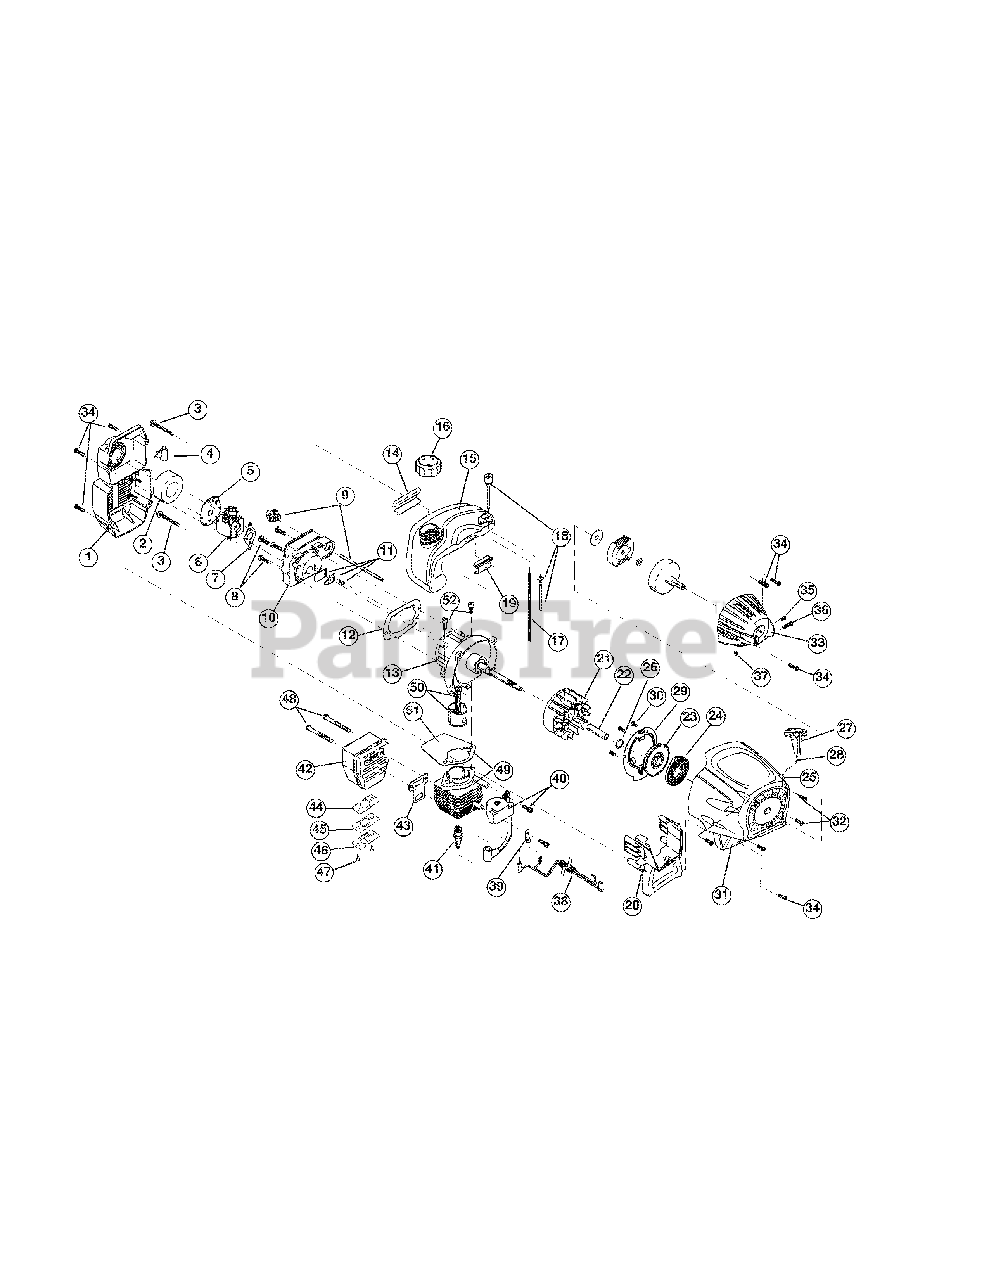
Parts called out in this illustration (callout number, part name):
1	Air Cleaner Cover Assembly (includes 2 & 34)
2	Air Cleaner Filter
3	Carburetor Mounting Screw Assembly
4	Choke Extension
5	Choke Plate
6	Carburetor Assembly (includes 7 & 18)
7	Carburetor Gasket
8	Carb Mount Screw
9	Primer & Hose Assembly
10	Carb Mount Assembly (includes 8, 11 & 12)
11	Reed Assembly
12	Carburetor Mount Gasket
13	Crankcase Service Assembly (includes 8)
14	Rear Mounting Pad
15	Fuel Tank Assembly (includes 16-18)
16	Fuel Cap Assembly
17	Fuel Return Line
18	Fuel Line Assembly
19	Front Mounting Pad
20	Shroud Extension & Stand (includes 34)
21	Flywheel Assembly
23	Recoil Pulley Assembly
24	Recoil Spring
25	Rope Guide
26	Pulley Retainer
27	Pull Handle
29	Pressure Plate Assembly
30	Plate Screw
31	Starter Housing Assembly (includes 23-30, 32 &34)
32	Housing Screw
33	Clutch Cover Assembly (includes 37-40)
34	Cover Screw
35	Anti-Rotation Screw
36	Clamping Screw
37	Clamping Nut
38	Wire Leads and Sleeve
39	Ground Tab
40	Module Assembly
42	Muffler Assembly (includes 46-51)
43	Exhaust Gasket
44	Spark Arrestor Screen
45	Exhaust Hood Diverter
46	Exhaust Hood
47	Screws
48	Muffler Mounting Bolts
49	Cylinder Assembly (includes 51 & 52)
50	Piston and Rod Assembly
51	Cylinder Gasket
52	Cylinder Bolt
